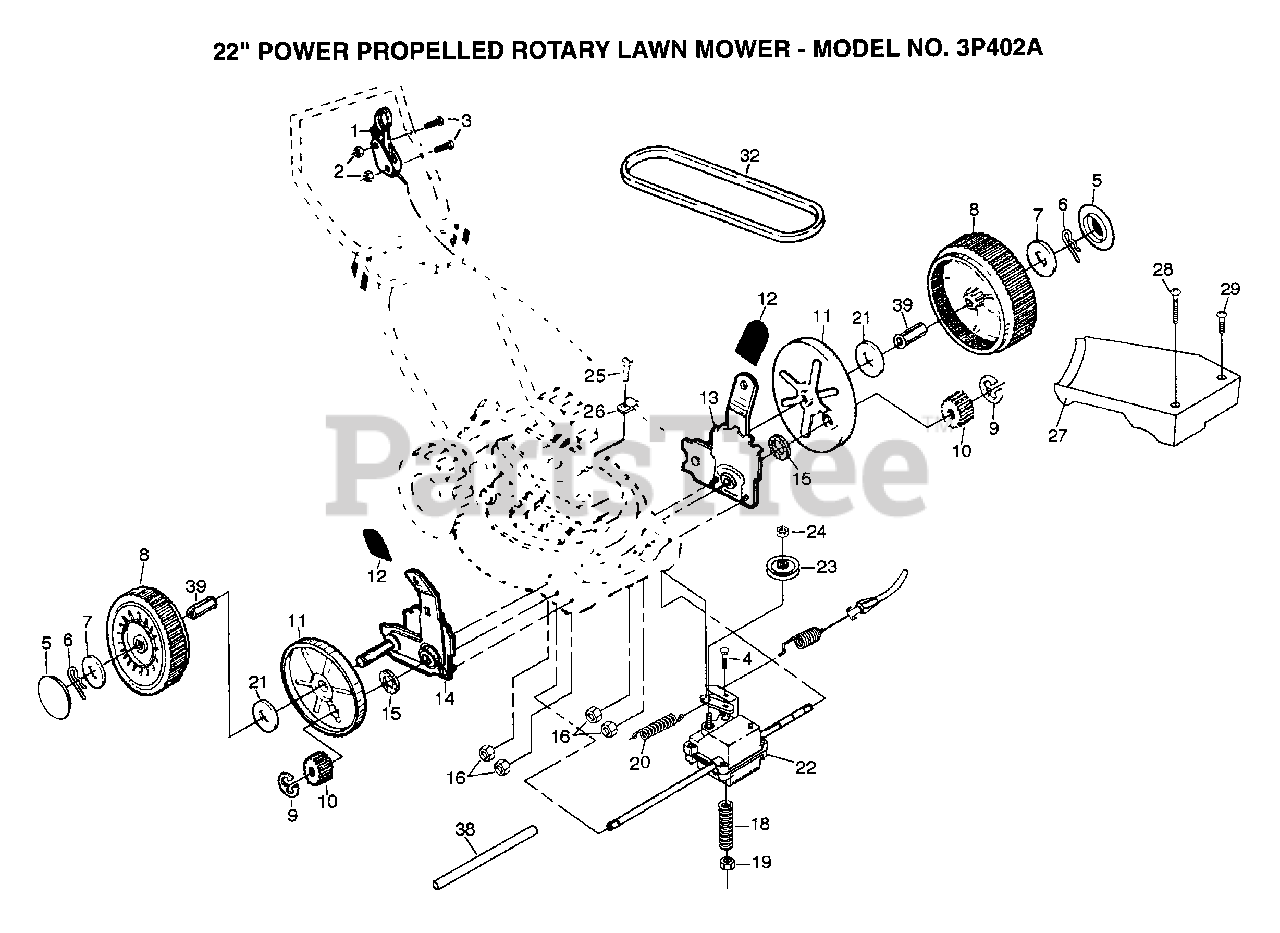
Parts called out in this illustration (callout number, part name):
1	CONTROL.DRIVE
2	LOCKNUT
3	SCREW
4	BOLT.1/4-20X2.0
5	HUB CAP
6	RETAINER CLIP PM
7	WASHER
8	WHEEL.8X2.LP.PR
9	E-RING.7/16.RE.
10	PINION.GEAR
11	DUST SHROUD PM
12	KNOB PM
15	WASHER PM
18	SPRING.TENSION
20	SPRING
21	WASHER FLUT
23	PULLEY.DRIVEN
24	LOCKNUT
25	TAPPING SCREW
26	GUIDE CLIP PM
27	COVER DRIVE BLK
38	DRV SHAFT TUBE PM
39	BUSHING.HEX
